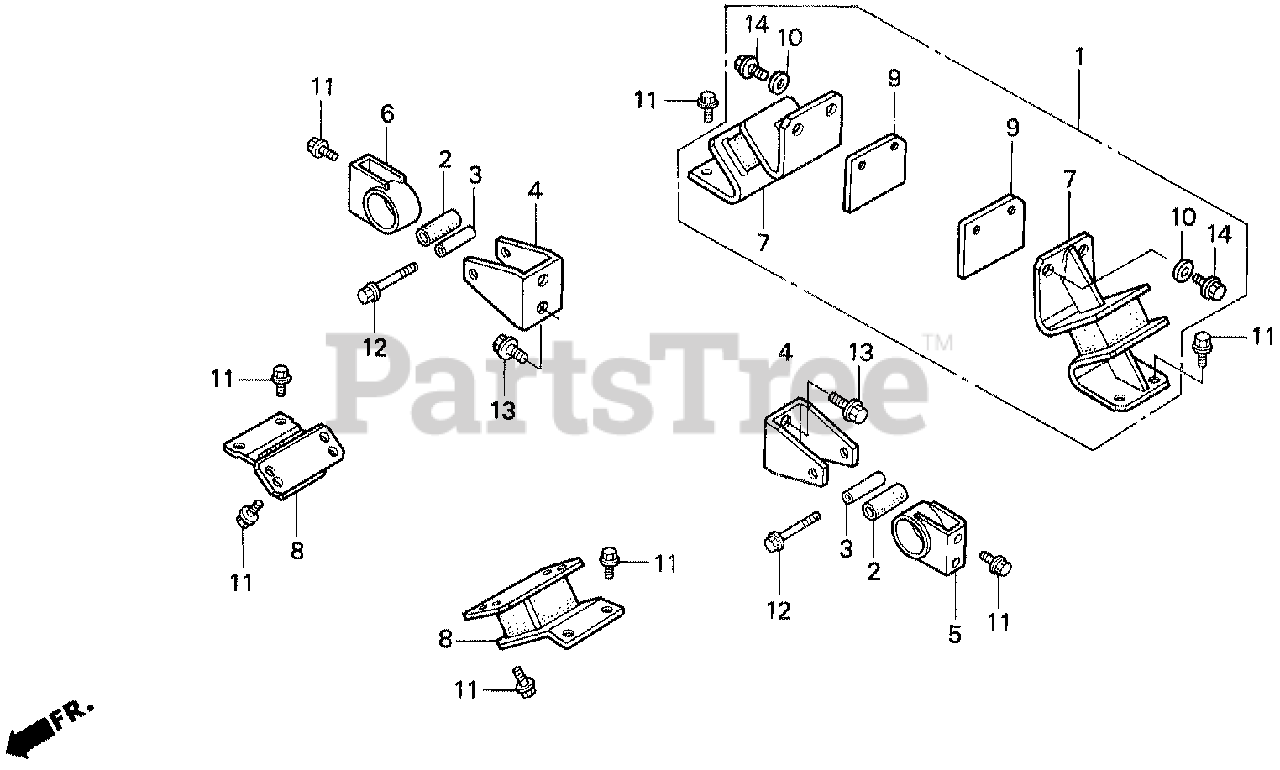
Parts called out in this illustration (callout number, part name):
1	MOUNT KIT, RADIATOR Use from Frame SN 1001951.
2	RUBBER, STOPPER
3	COLLAR, DISTANCE
4	PLATE, STOPPER
5	STAY, R. BUMP STOP
6	STAY, L. BUMP STOP
7	RUBBER (LOWER)
7	MOUNT KIT, RADIATOR
8	RUBBER, GENERATOR (LOWER)
9	PLATE, RUBBER
10	WASHER, PLAIN (10MM)
11	BOLT, FLANGE (8X16)
12	BOLT, FLANGE (8X70)
13	BOLT, FLANGE (10X20)
14	BOLT, FLANGE (10X25)
